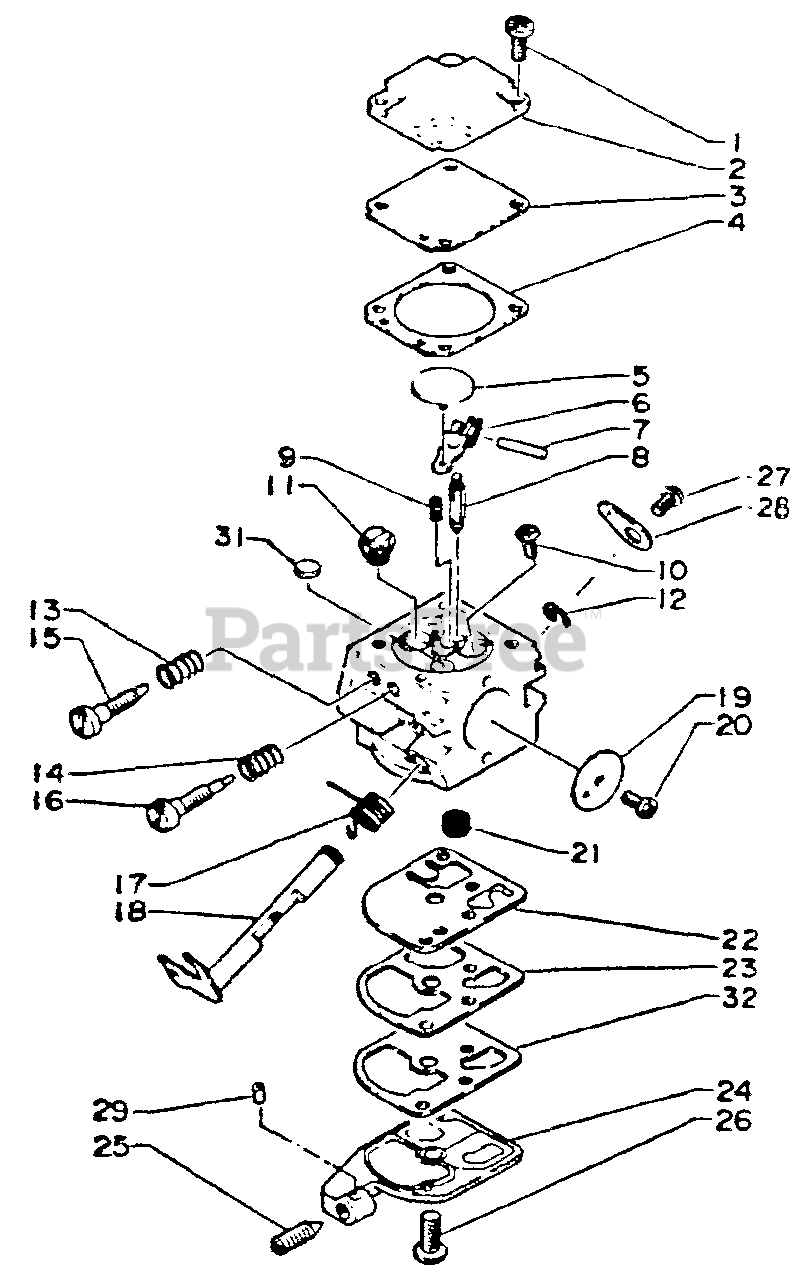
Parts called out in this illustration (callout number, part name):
1	SCREW
2	COVER, METERING
3	Diaphragm
4	GASKET, DIAPHRAGM
5	PLUG, WELCH
6	LEVER, METERING
7	PIN
8	Needle valve
9	SPRING
10	SCREW, METERING LEVER PIN
11	NOZZLE, CHECK VALVE
12	RING, RETAINING
15	NEEDLE - HIGH SPEED
16	NEEDLE - LOW SPEED
17	SPRING, RETURN
18	SHAFT, THROTTLE
19	VALVE, THROTTLE
20	SCREW
21	SCREEN, SPARK ARRESTOR
22	DIAPHRAGM, PUMP
23	GASKET, FUEL PUMP
24	BASE, PUMP
25	SCREW, IDLE ADJUST
26	SCREW, PUMP COVER
28	LEVER, THROTTLE
29	PIECE, FRICTION
31	PLUG, WELCH
32	Diaphragm surge
32	REPAIR KIT
32	DIAPHRAGM/GASKET KIT
